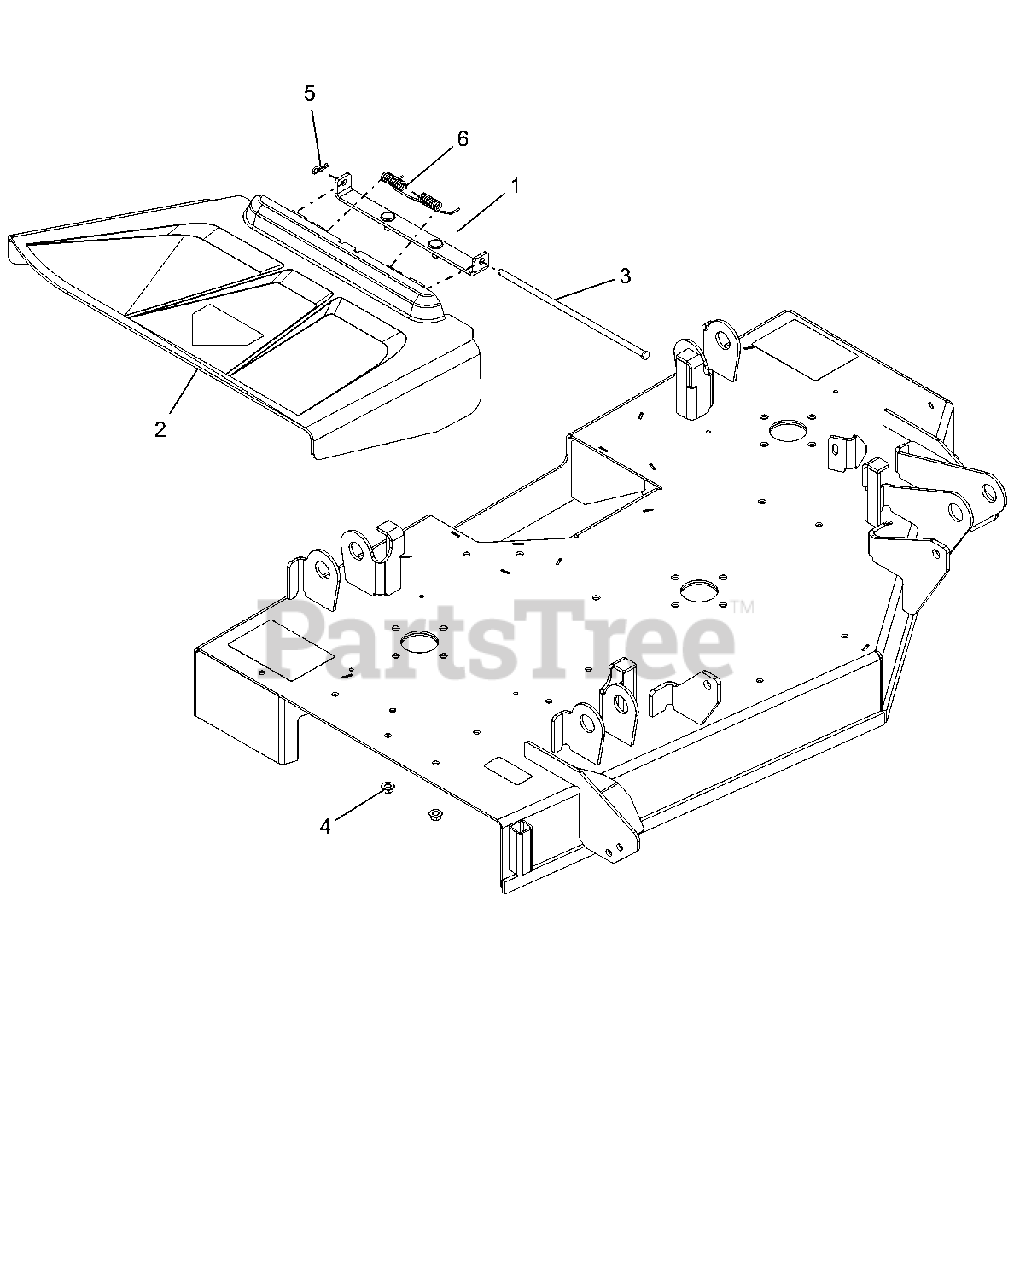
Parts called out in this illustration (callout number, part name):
1	WLDMT, CHUTE MT BRKT
2	CHUTE, SIDE DISCHARGE
3	PIN, 5/16 X 10.5
4	@NUT-LK-TOP-FLG .31-18 YWZC
5	PIN-HAIR INT .08X.18X1.18 YWZC
6	SPRING-TORSION
